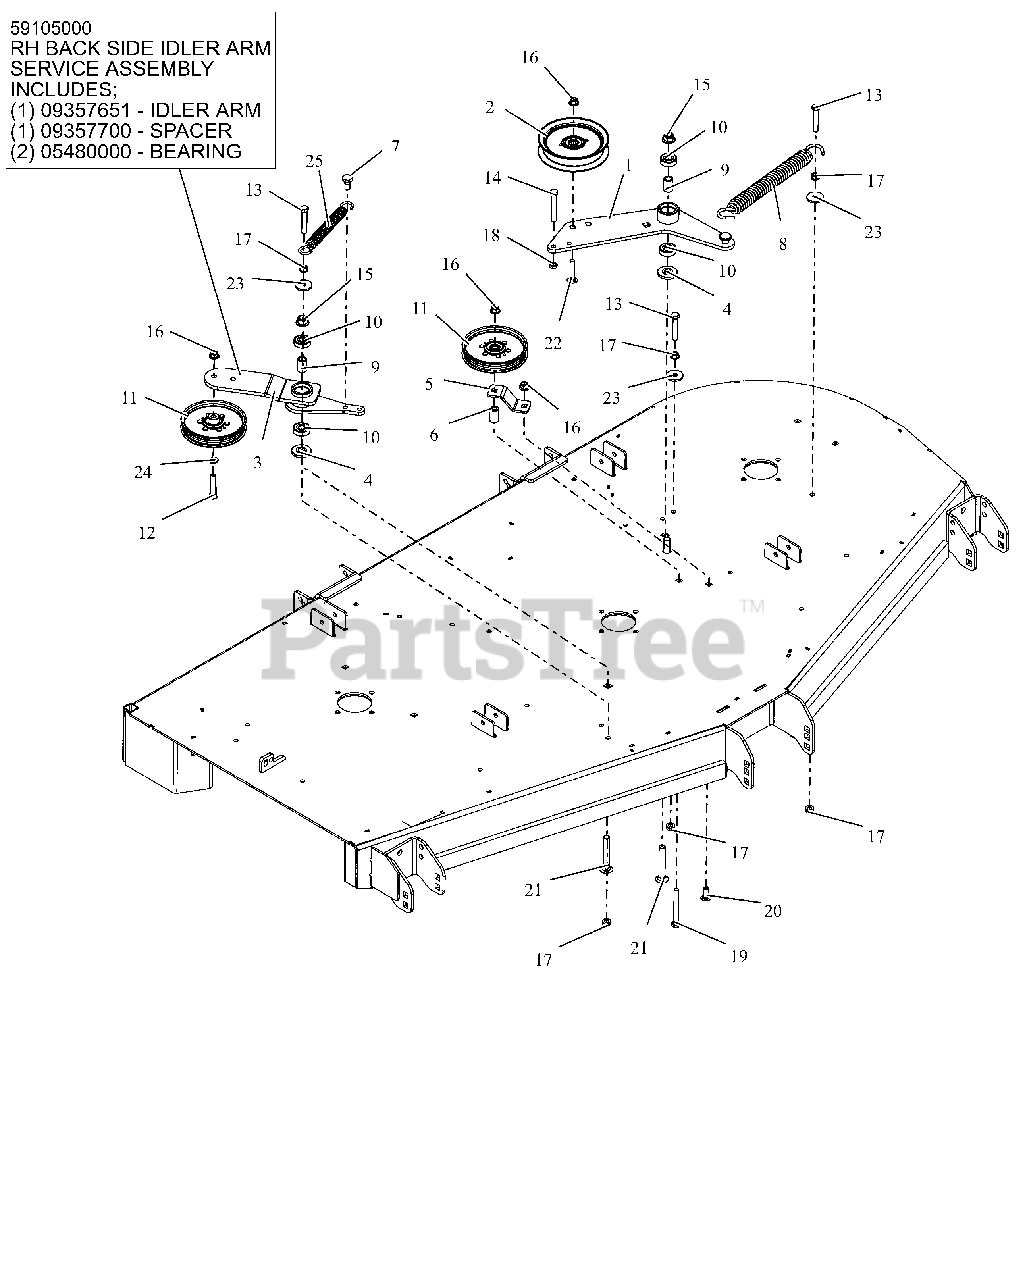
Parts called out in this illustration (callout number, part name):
1	DECK PTO IDLER ARM WLDMT - BLK
2	IDLER, FLAT 5.00"
3	DECK RH IDLER ARM WMT - BLK
3	RH BACKSIDE IDLER ARM ASSEMBLY
4	SPACER, IDLER ARM
5	PTO FIXED IDLER MTG BRKT -RED
6	BUSHING, SLV .380X.750X1.190
7	BLT,SHLDR EP .38-16X.30 HEX YZ
8	SPRING, EXTENSION
9	SPACER .510 X .75 X 1.1485
10	BRG-BALL .500X1.38X.437
11	PULLEY, FLAT IDLER
12	BLT,HEX .38-16X2.00 G5 ZCC
13	BLT,HEX .38-16X2.25 G5 ZCC
14	BLT, HEX .38-16X2.75 G5 ZCC
15	NUT,NYL-FLG .50-13 GF ZCC
16	NUT,NYL-FLG .38-16 GF ZCC
17	NUT, SPNLK-FLG .38-16 G5 ZCC
18	NUT-JAM .375-16 G2 ZCC
19	BLT,RHSSN .38-16X3.50 G5 ZCC
20	BLT,RHSSN .38-16X1.00 G5 ZCC
21	BTL,RHSSN .500-13 X 3.25 G5 ZCC
22	BLT,RHSSN.375-16X2.00 G5 ZCC
23	WSHR,FLT .406X1.375X.135 ZCC
24	WSHR,FLT .406X.812X.065 ZCC
25	SPRING, EXTENSION
